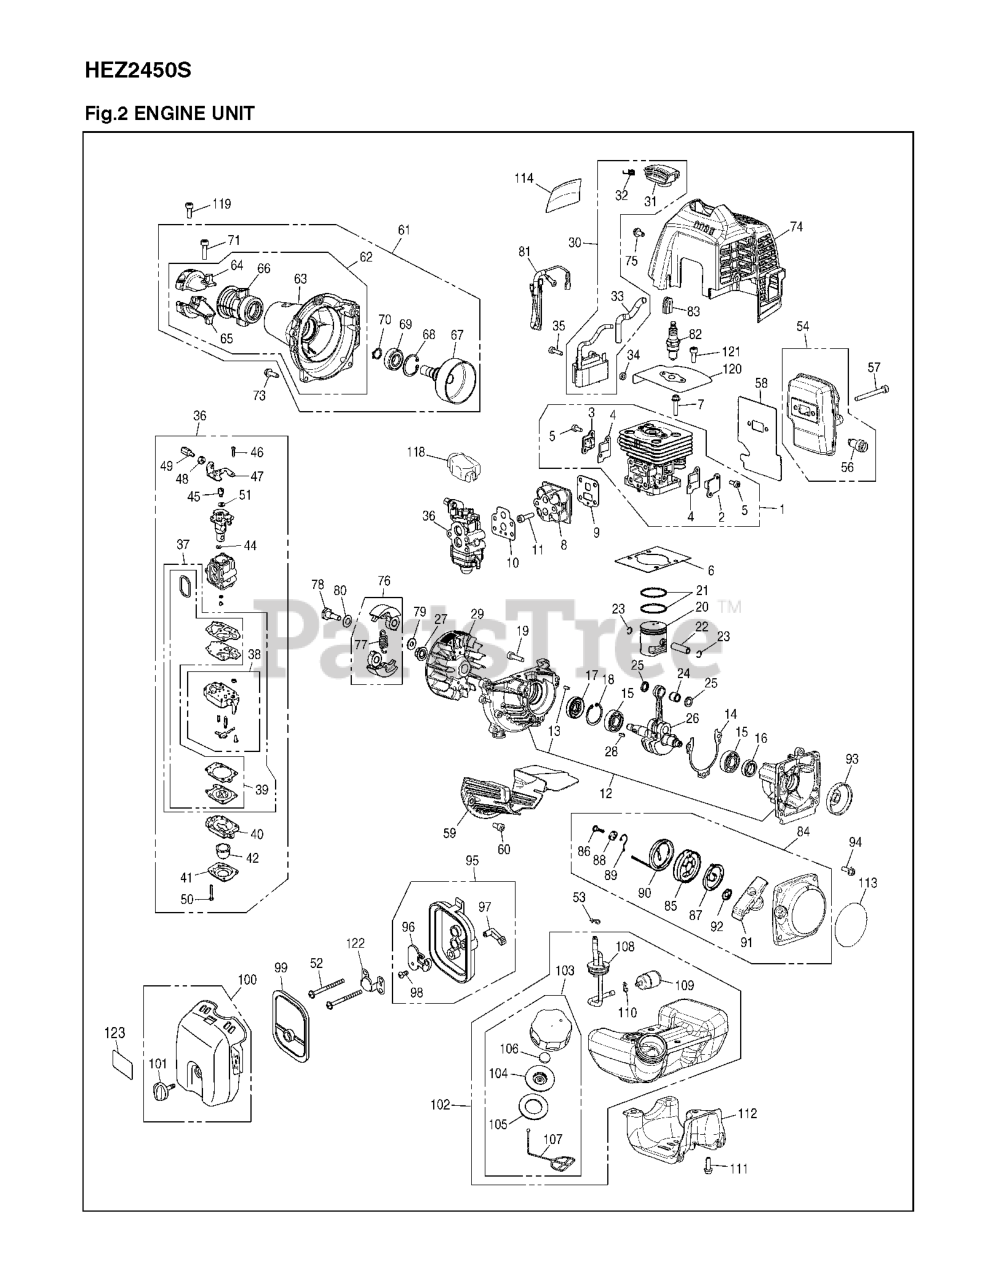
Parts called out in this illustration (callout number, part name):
1	CYLINDER COMPLETE
2	COVER, TR-S
3	COVER, TR-F
4	GASKET, TR
5	BOLT
6	GASKET, BASE
7	BOLT
8	INSULATOR
9	INSULATOR GASKET(R-848F0814B0)
10	GASKET, CARB
11	BOLT TORX
12	CRANKCASE-C
13	PIN
14	GASKET, CASE
17	SEAL
22	PIN
26	CRANKSHAFT-C
27	NUT
28	KEY
31	CAP
34	SPACER
36	CARBURETOR (RPLS 848F088100)
37	REBUILD KIT
39	GASKET KIT
41	1OVER
44	RING
45	SWIVEL
46	SCREW
47	BRACKET
48	NUT
49	ADJUSTER
51	WASHER
52	BOLT TORX
53	CLIP
54	MUFFLER
56	ARRESTER
58	GASKET, MUFFLER
61	HOUSING ASSY (RPLS T155131000)
62	HOUSING
64	BRACKET (A) (RPLS T170031211)
65	BRACKET (B)
67	DRUM (RPLS 481031120-22)
69	BEARING
74	COVER, ENGINE
75	BOLT (RPLS T495051010-11)
76	SHOE COMP
81	CORD-COMP
82	PLUG CMR7H
84	RECOIL ASSY
87	SPRING, SPIRAL
88	COLLAR
89	SWING ARM
92	PLATE.STOPPER
95	CLEANER BODY ASSY
96	PLATE, CHOKE
98	SCREW
99	ELEMENT
100	%CLEANER COVER ASSY
101	Cleaner Knob
102	TANK ASSY
104	HOLDER-A
108	PIPE-C
109	FILTER
110	CLIP
112	GUARD
113	LABEL, RECOIL
123	LABEL
